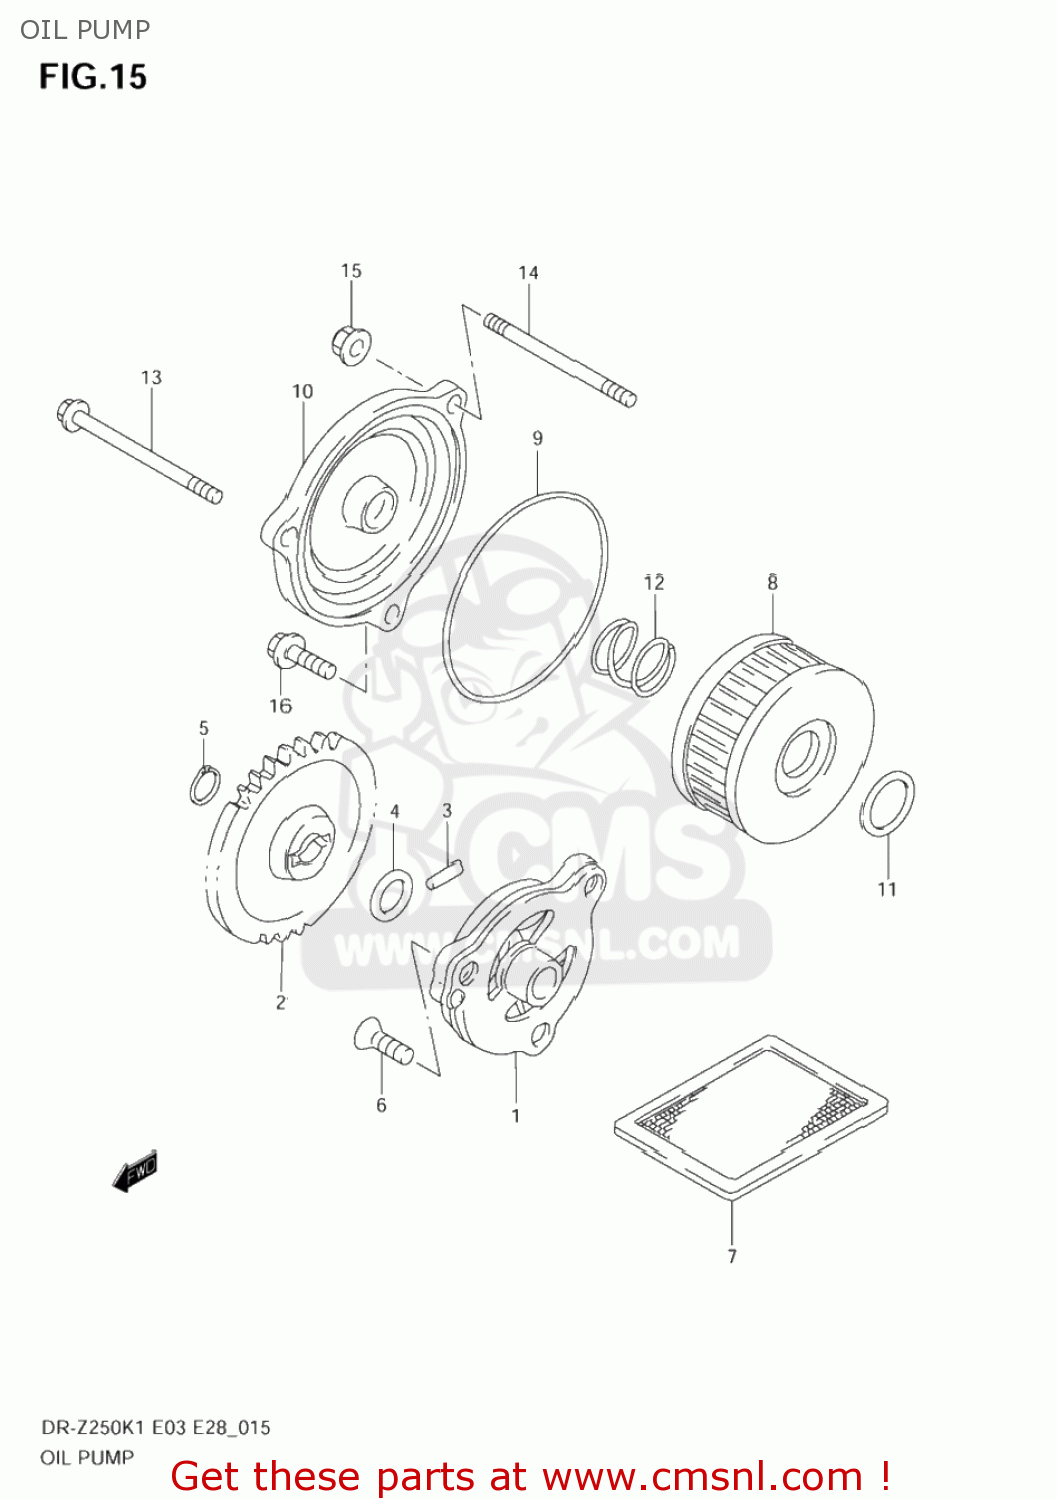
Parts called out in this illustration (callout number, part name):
1	PUMP ASSY,ENGINE OIL
2	GEAR,OIL PUMP DRIVEN(NT:33)
3	PIN(4X15.8)
4	SHIM(10X18X0.5)
5	CIRCLIP,10MM
6	SCREW ,6X16
7	STRAINER,ENGINE OIL
8	FILTER ASSY,ENGINE OIL
9	O RING(D:2.4,ID:73)
10	CAP,OIL FILTER
11	O RING(D:2.4,ID:15.8)
12	SPRING
13	BOLT
14	BOLT,STUD
15	NUT
16	SCREW
